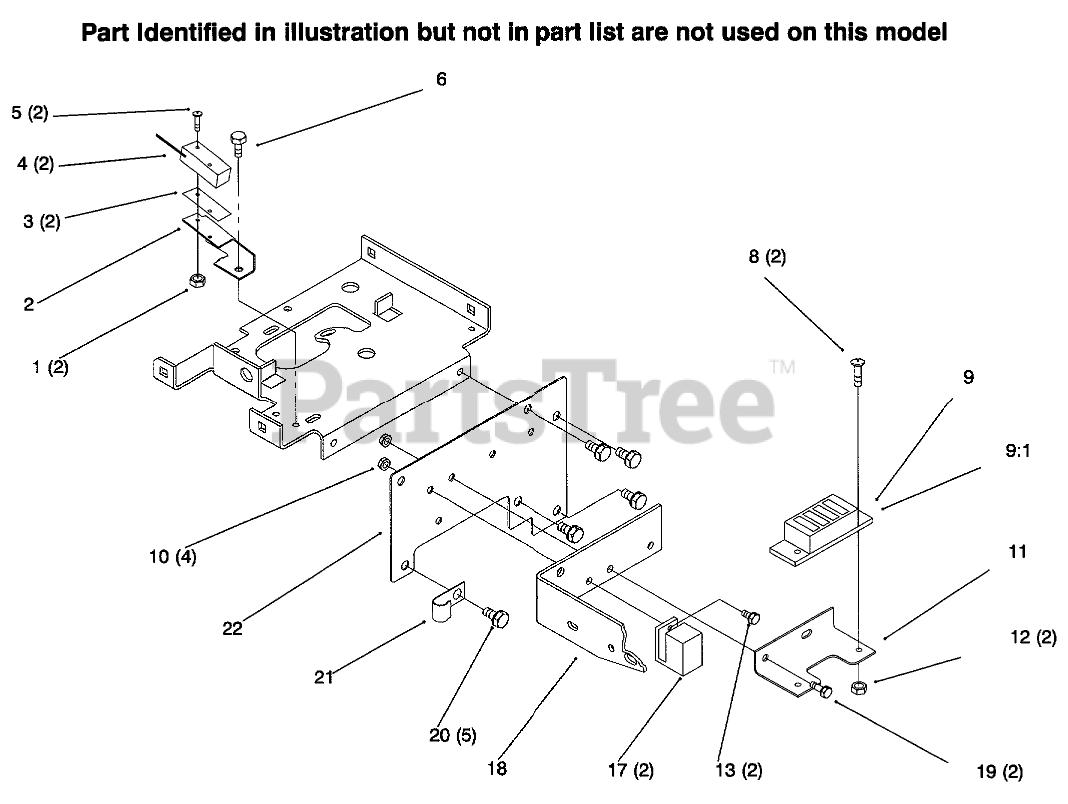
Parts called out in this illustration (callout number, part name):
1	NUT-HEX
2	BRACKET-SWITCH
3	BARRIER - SWITCH
4	SWITCH
5	SCREW-PHL 4-40X1 1/4
6	SCREW-HWH
8	SCREW-PAN
9	WIRING-HARNESS & DIA
9:1	FUSE-HOLDER 4 WAY
10	NUT-LOCK, NI
11	BRKT-FUS HLDERB
12	Nut
13	SCREW1/4-20X5/8 WHIZ
17	RELAY
18	BRACKET-BELTB
19	SCREW-HH
20	Bolt
21	CLIP
22	Front Plate
